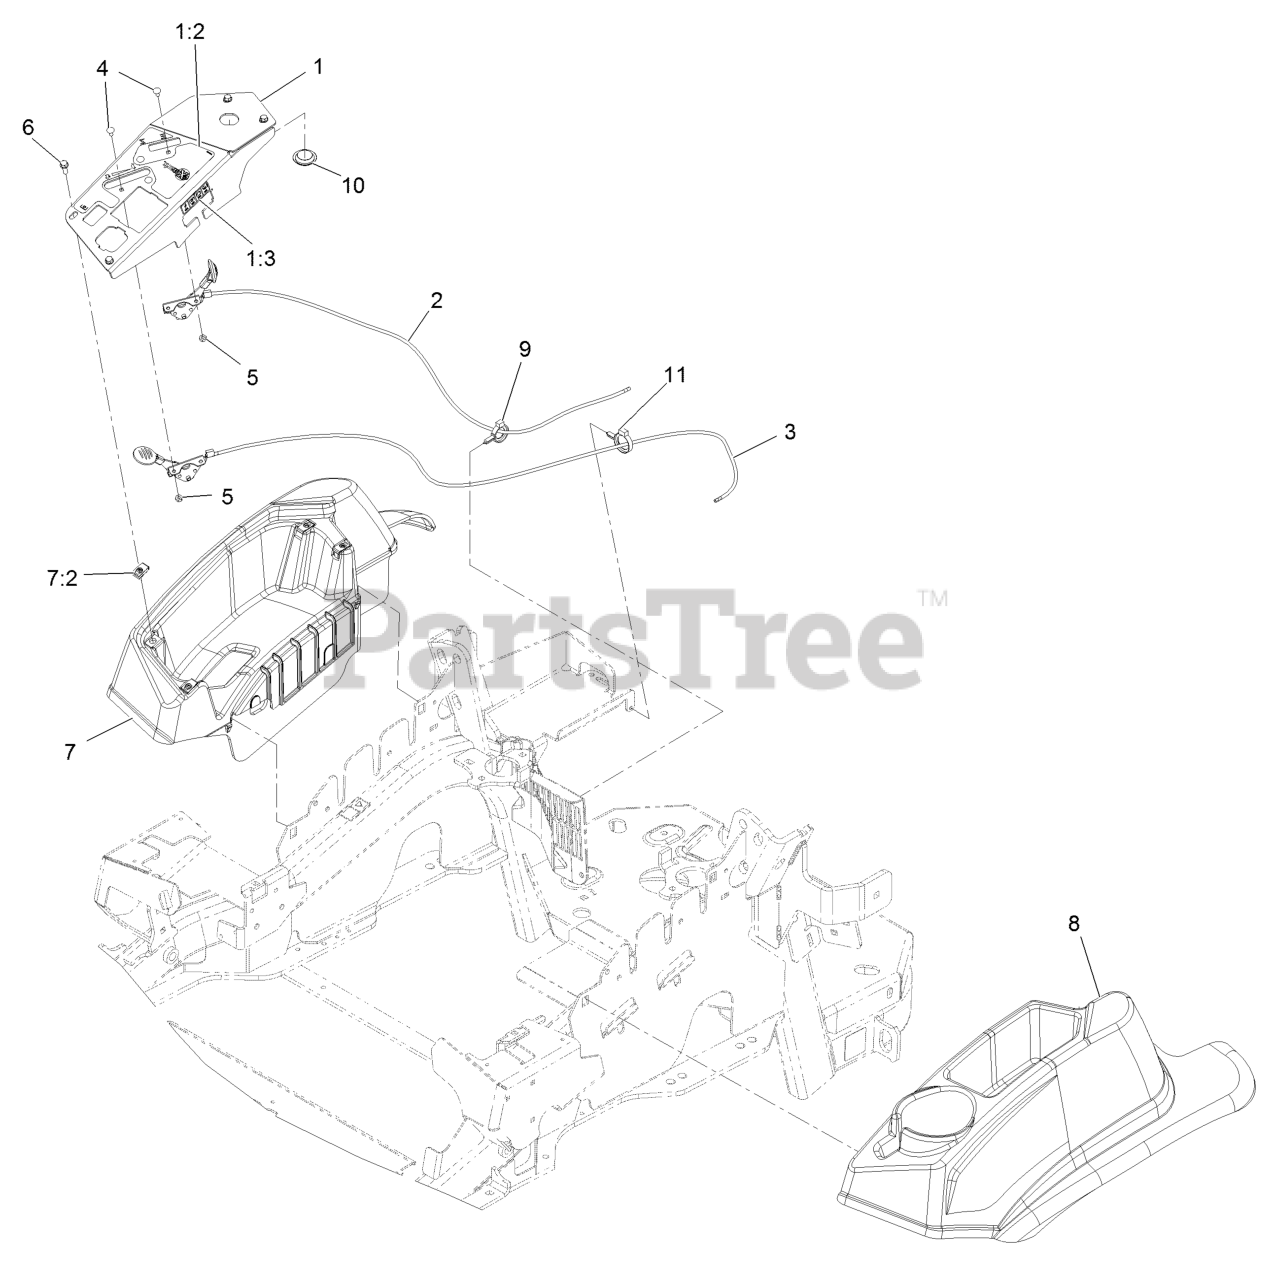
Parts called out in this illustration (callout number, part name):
1	ASM,CONSOLE PANEL W/DECAL
1:2	DECAL-CONTROL PANEL NON-E
1:3	DECAL-FUSES
2	ASM, CHOKE CABLE
3	ASM,THROTTLE CABLE
4	BOLT-CARR
5	NUT-LOCK, NI
6	SCREW-HWH
7	CONSOLE,RH AS ASM
7:2	Nut-Retainer-Panel 1/4-20
8	CONSOLE, LH AS
9	CLAMP-HOSE
10	PLUG-PLASTIC
11	CLAMP-HOSE
